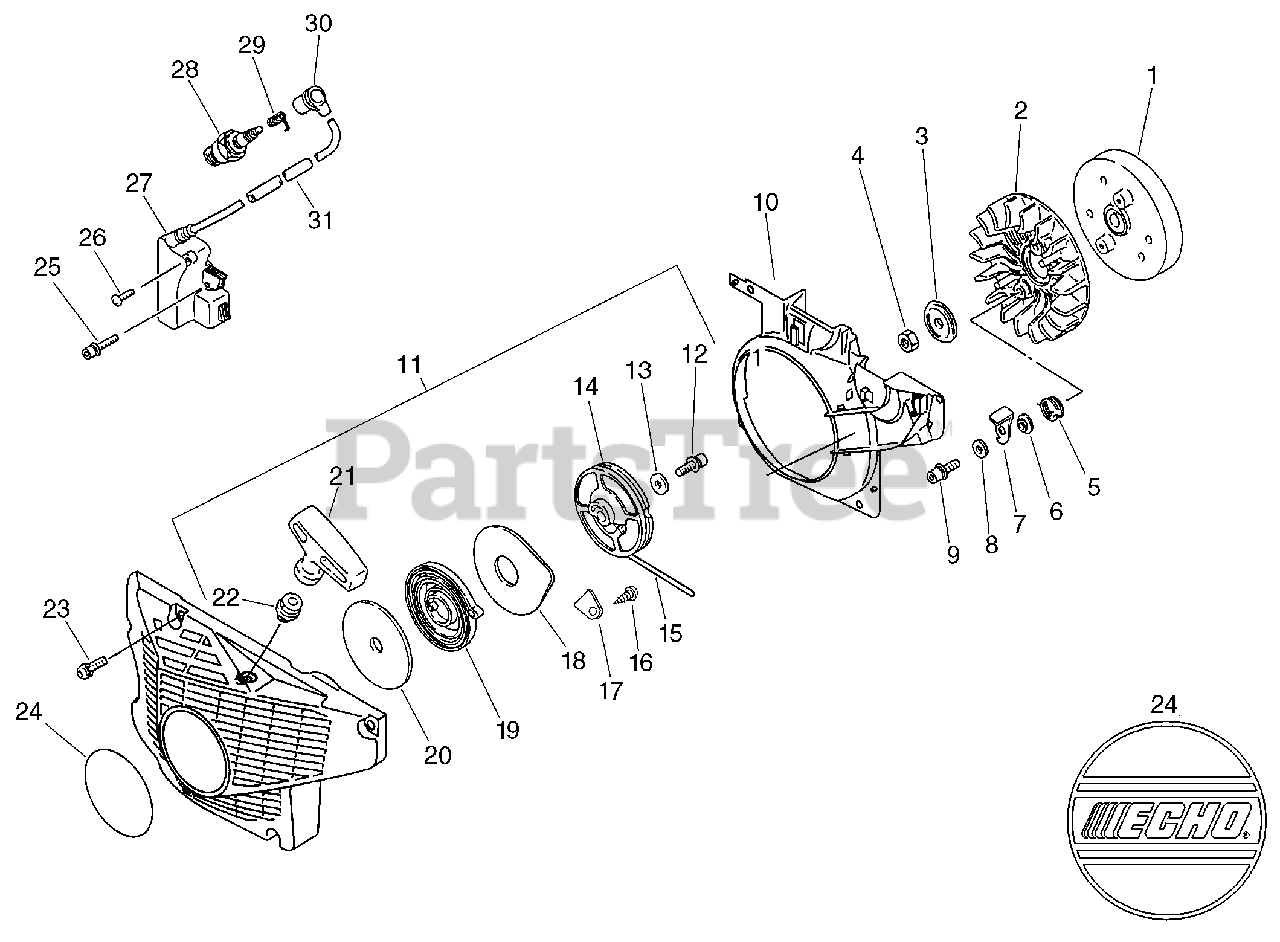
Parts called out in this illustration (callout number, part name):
1	FLYWHEEL
3	WASHER 8.2×31×0.8
5	SPRING, RETURN
7	PAWL, STARTER
8	WASHER 5.5×12×0.8
9	BOLT 5×14
10	COVER, FAN
11	STARTER ASSY
12	BOLT 5×14
13	WASHER 5.5×12×0.8
14	REEL, ROPE
15	ROPE, STARTER
16	SCREW 4×8
17	PLATE, EYE
18	PLATE, STARTER
19	SPRING, RECOIL
20	PLATE, STARTER
21	GRIP, STARTER
22	GUIDE, ROPE
23	BOLT 5×20
24	LABEL, ECHO
25	BOLT 4×20
26	SCREW 4×8
27	COIL, IGNITION
28	SPARK PLUG - BPMR7A
29	TERMINAL, SPARK PLUG
30	CAP, SPARK PLUG
